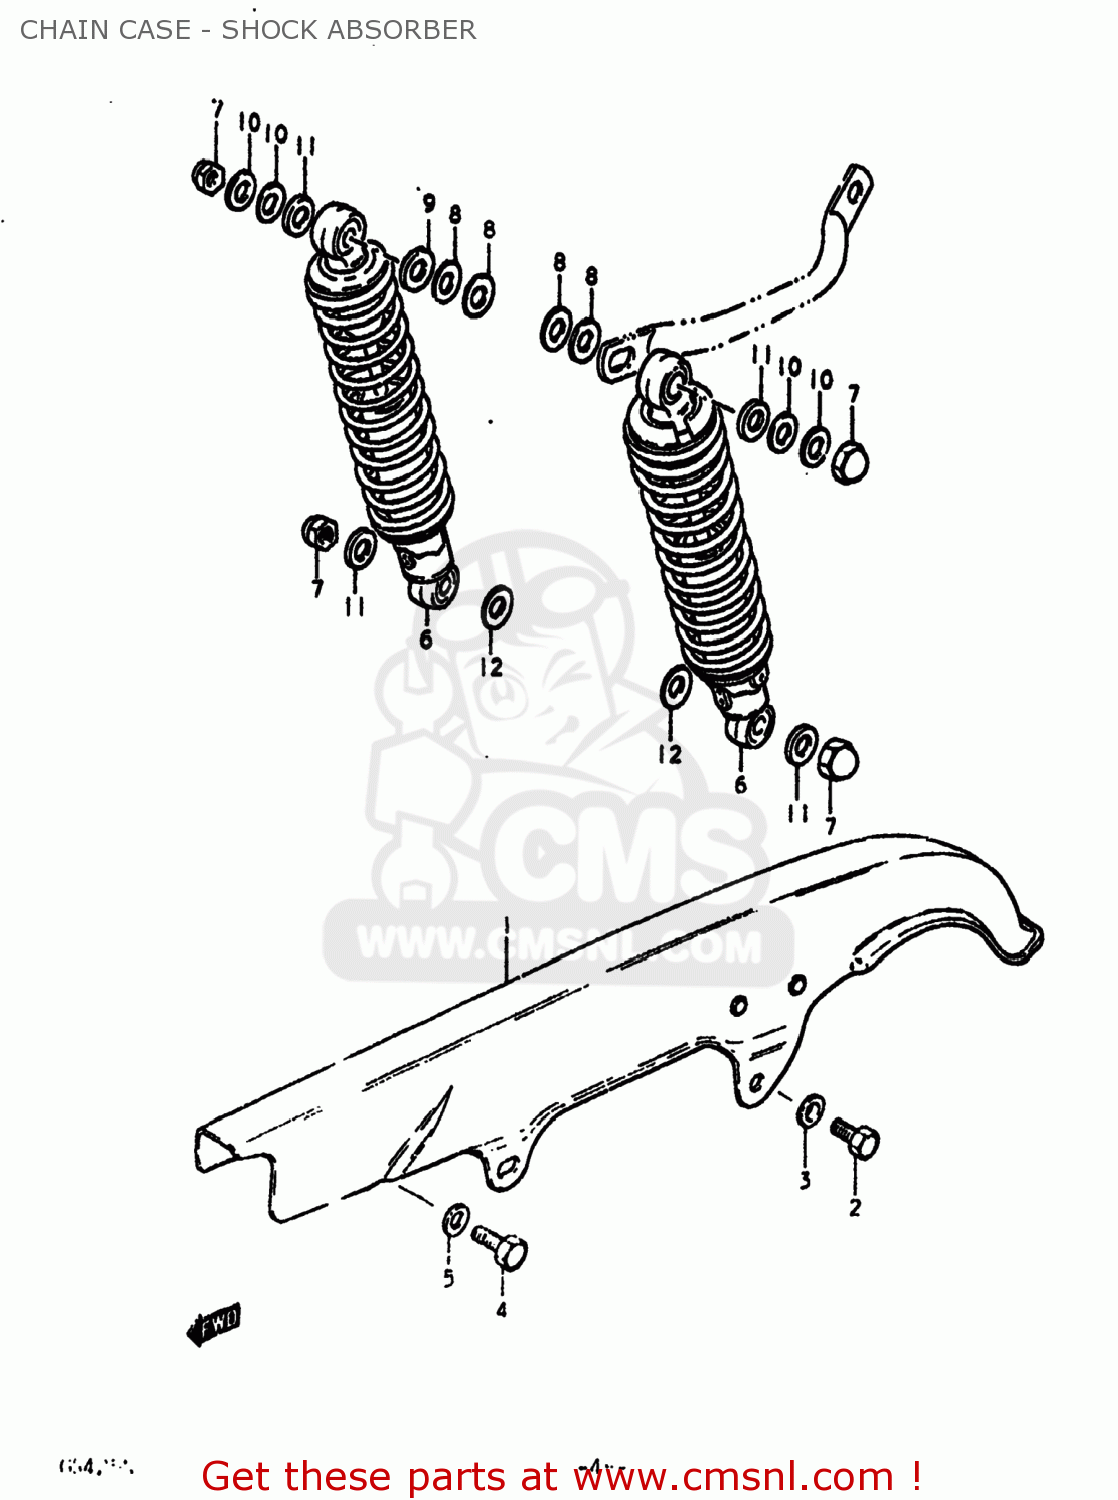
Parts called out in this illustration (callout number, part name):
1	CASE,CHAIN
2	BOLT(6X8)
3	WASHER
4	BOLT
5	WASHER(6.5X18X1)
6	ABSORBER ASSEMBLY,REAR SHOCK
7	NUT, LOWER LH
8	WASHER
9	WASHER (12.5X24X3.2)
10	WASHER
11	WASHER(10.5X24X3.2)
12	WASHER (12.5X24X1.6)
